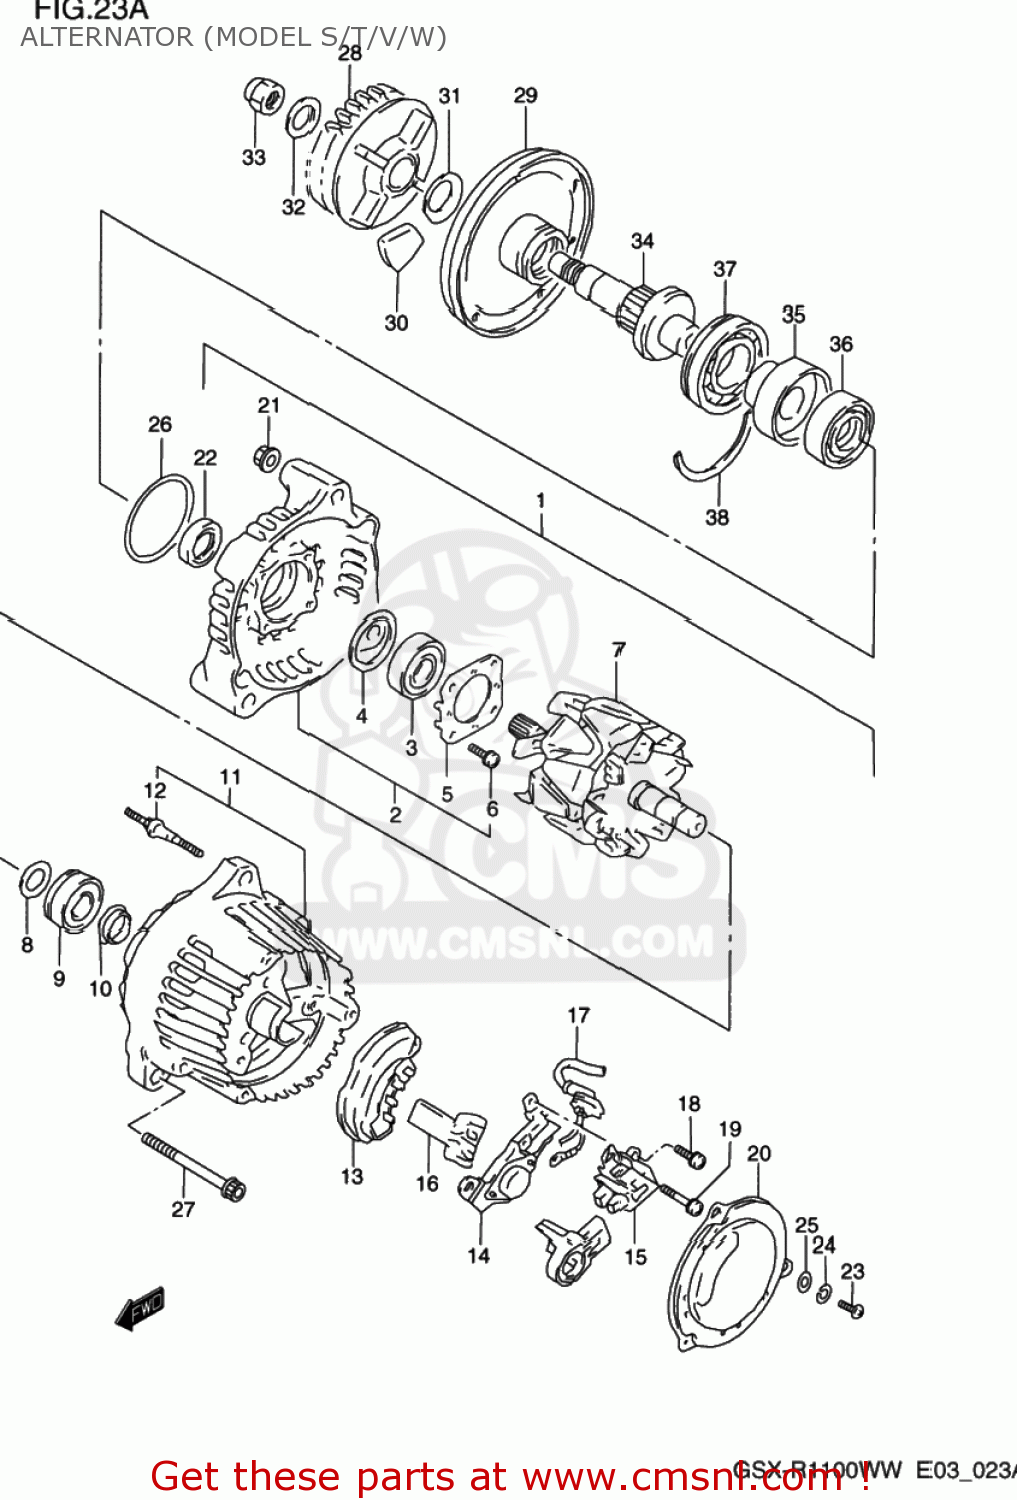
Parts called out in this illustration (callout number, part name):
1	ALTERNATOR ASSY
2	FRAME,DRIVE END
3	BEARING
4	COVER,BEARING
5	RETAINER,BEARING
6	SCREW,BEARING RETAINER
7	ROTOR ASSEMBLY
8	COVER,BEARING
9	BEARING
10	COVER(2)
11	FRAME,END
12	STUD BOLT
13	HOLDER,RECTIFIER
14	REGULATOR
15	HOLDER,BRUSH
16	COVER,RECTIFIER
17	WIRE,LEAD
18	SCREW 4X6
19	SCREW
20	COVER
21	NUT
22	SERVICE KIT(A)
23	SCREW
24	LOCK,WASHER
25	WASHER
26	O RING
27	BOLT
28	GEAR,GENERATOR DRIVEN
29	HOUSING,GENERATOR DAMPER
30	DAMPER,GENERATOR
31	WASHER
32	WASHER
33	NUT
34	SHAFT,GENERATOR DRIVE
35	HUB,GENERATOR DRIVE
36	COUPLING COMP,GENERATOR
37	BEARING(25X52X13)
38	C RING
